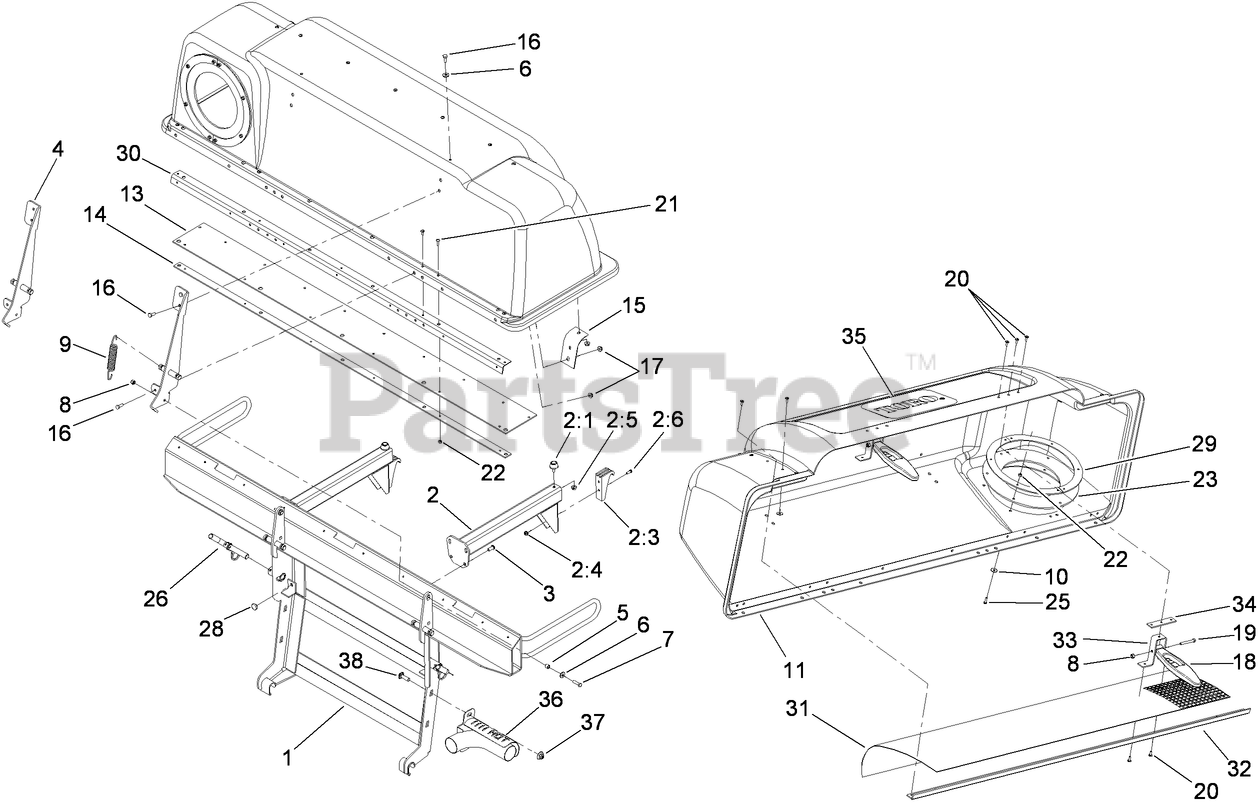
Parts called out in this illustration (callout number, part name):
1	FRAME-TRIPLE BAGGER
2	BAG SUPPORT ASM
2:1	BUMPER
2:4	NUT-HF
2:5	NUT-HF
2:6	SCREW-PPH
3	SCREW-HSBH
5	SPACER
6	WASHER-FLAT
7	SCREW-HH
8	NUT-LOCK, NI
9	SPRING-EXTENSION
10	WASHER-FLAT
11	HOOD ASM
13	Seal-Hinge
14	Plate-Backing
15	Reinforcement-Hood, Bagger
16	SCREW-HH
17	NUT-HF
19	SCREW-HH
20	RIVET-BLIND
21	SCREW-HEAD, TRUSS
22	NUT-LOCK, NI
23	SEAL-TUBE
25	SCREW-PPH
26	PIN-MOUNT, BAGGER
28	BUMPER
29	CLAMP-SEAL
30	Stiffener-Bagger, Top
31	Screen-Bagger
32	Support-Screen
33	Bracket-Mount
34	Plate-Latch, Reinforcement
35	DECAL
36	DIVERTER-EXHAUST
37	NUT-FLANGE, NI
38	SCREW-CARR
